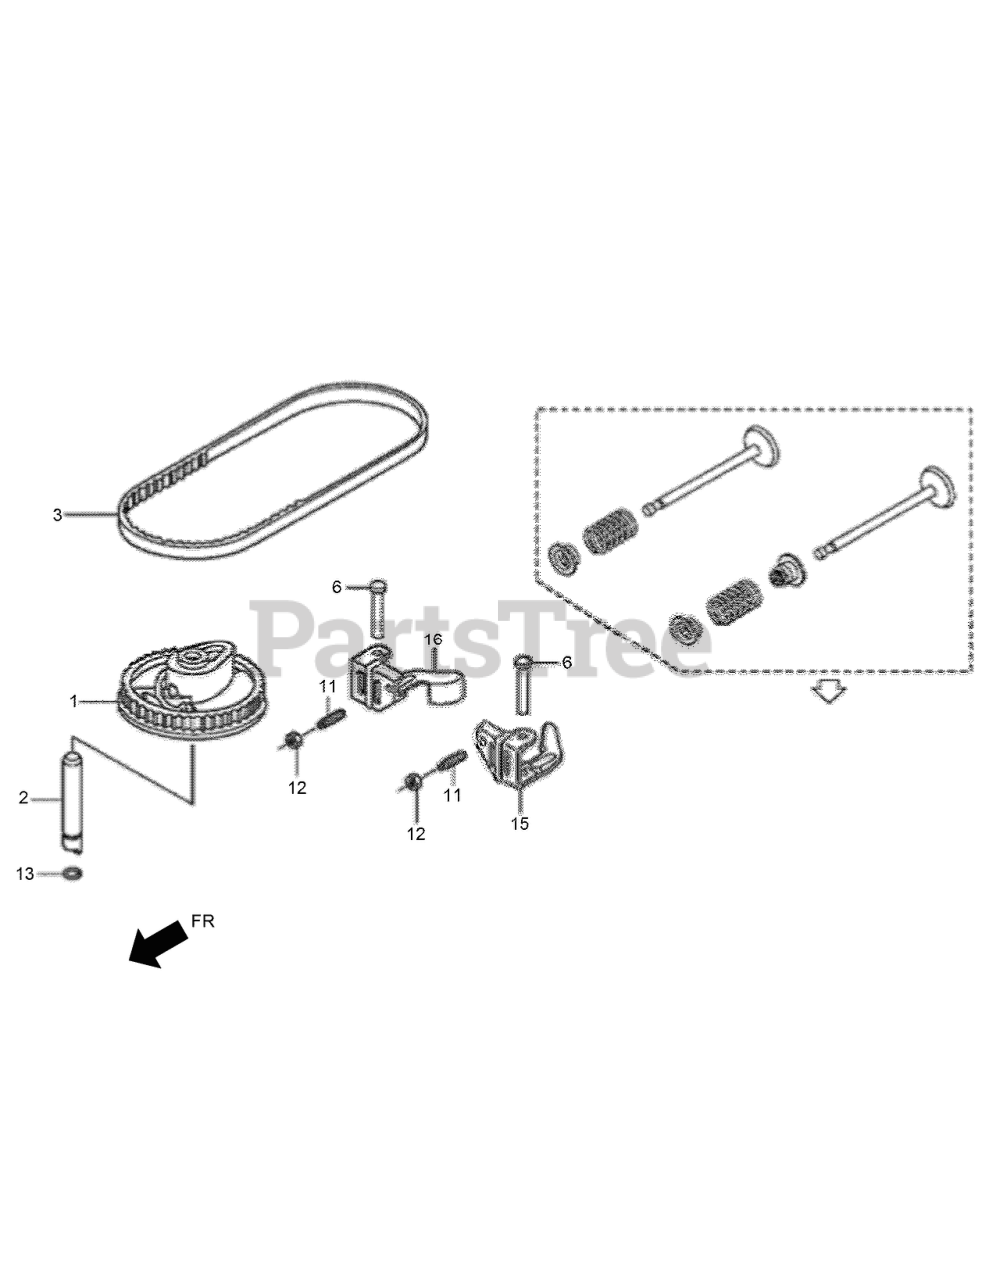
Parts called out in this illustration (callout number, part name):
1	PULLEY-CAMSHAFT
2	SHAFT-CAM PULLEY
3	BELT-TIMING
6	SHAFT-ROCKER ARM
11	SCREW-TAPPET ADJUSTING
12	NUT-TAPPET ADJUSTING
13	O-RING-6.8X1.9
15	ARM-INTAKE VALVE ROCKER
16	ARM-EXHAUST VALVE ROCKER
